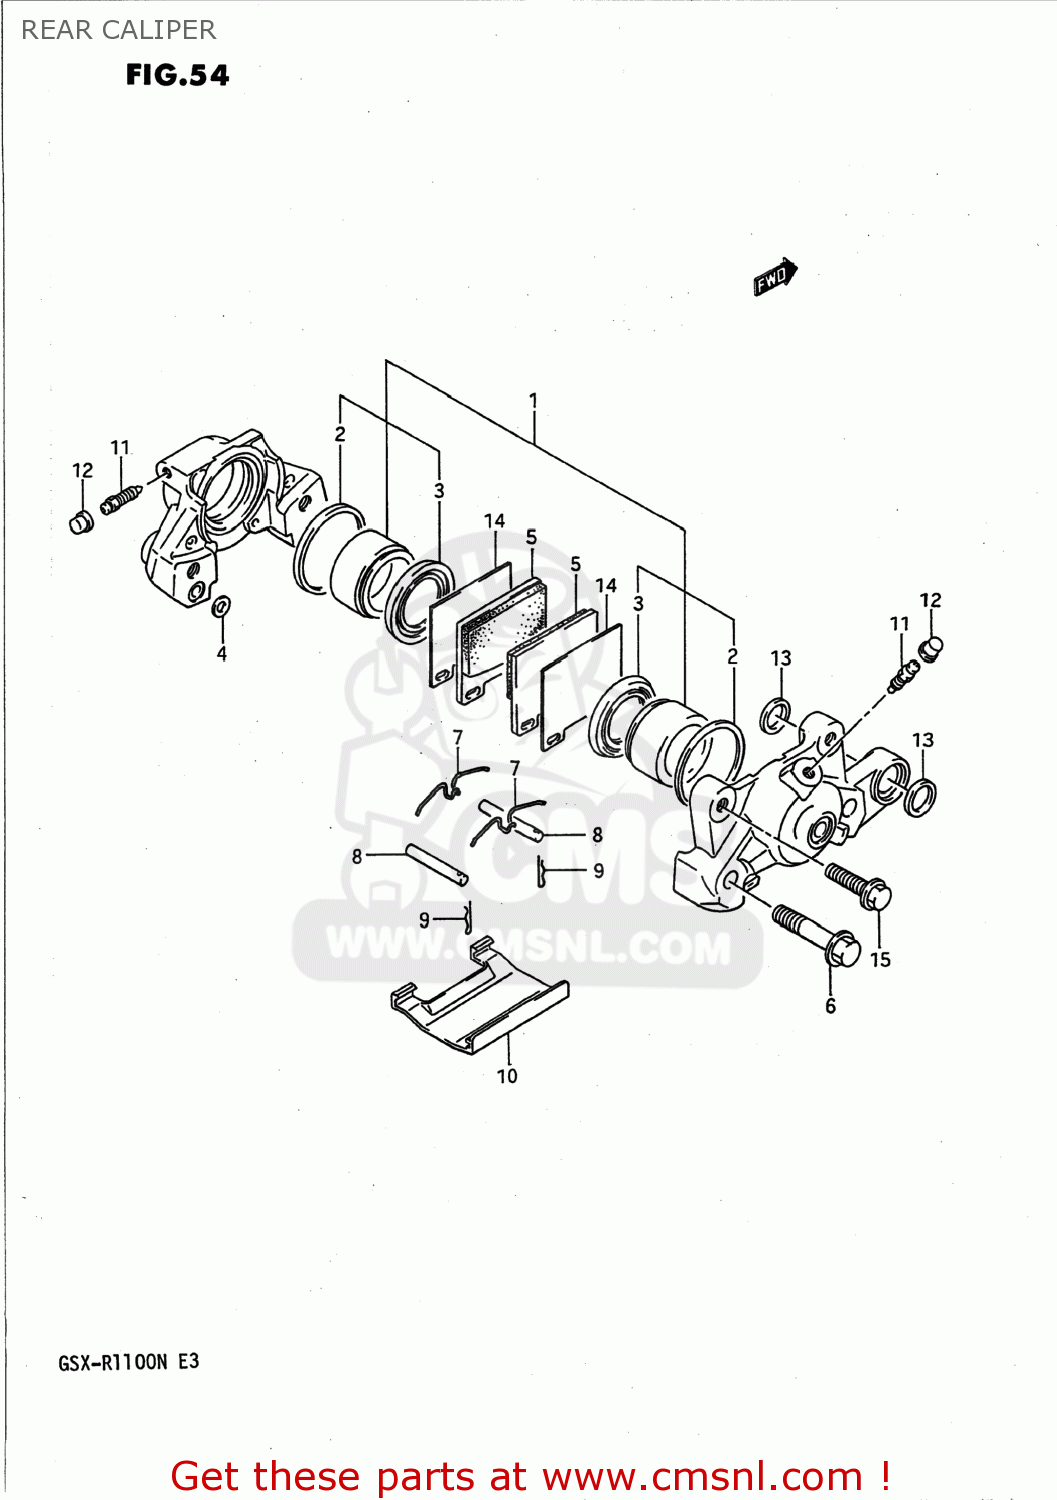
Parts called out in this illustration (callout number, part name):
1	PISTON SET
2	SEAL,PISTON
3	BOOT
4	SEAL,JOINT
5	PAD,BRAKE
6	BOLT
7	SPRING
8	PIN,PAD
9	CLIP,PAD PIN
10	COVER
11	BLEEDER
12	CAP,BREATHER
13	SEAL,RR CUSHION ROD LWR
14	SHIM,PAD
15	BOLT
